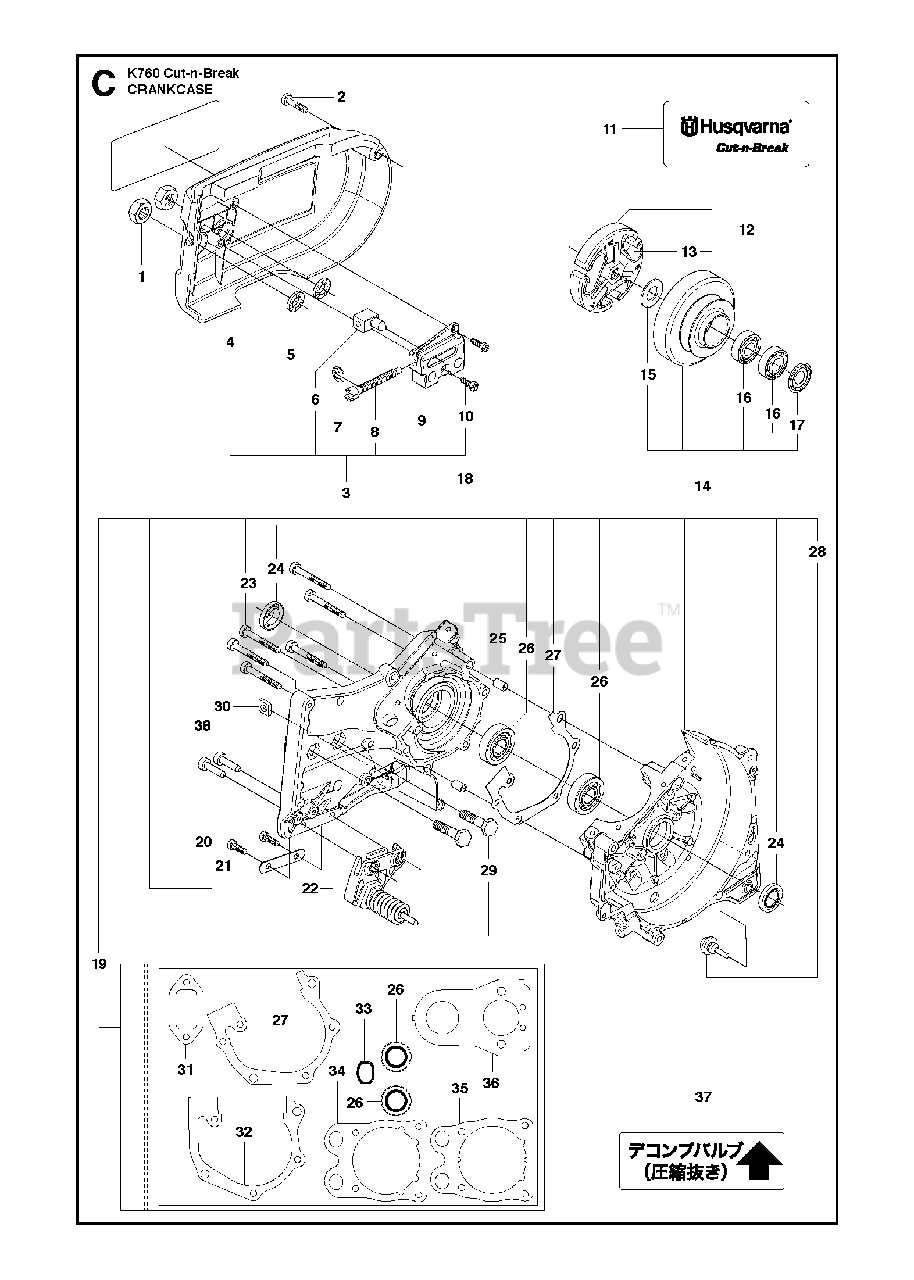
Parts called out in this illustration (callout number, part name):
1	HEXAGON NUT
2	SCREW CCRPANMO
3	BELT TENSIONER ASSY
4	CLUTCH COVER
10	SCREW ITXSCT
13	CLUTCH SPRING
14	DRIVING PULLEY ASSY
15	WASHER
16	BALL BEARING
18	CRANKCASE ASSY
19	GASKET KIT
20	SCREW ITXSCM
22	SPRING RETAINER
23	SCREW ITXSCM
24	SEALING RING
25	GUIDE BUSHING
26	BALL BEARING
31	GASKET
38	SCREW ITXSCM
